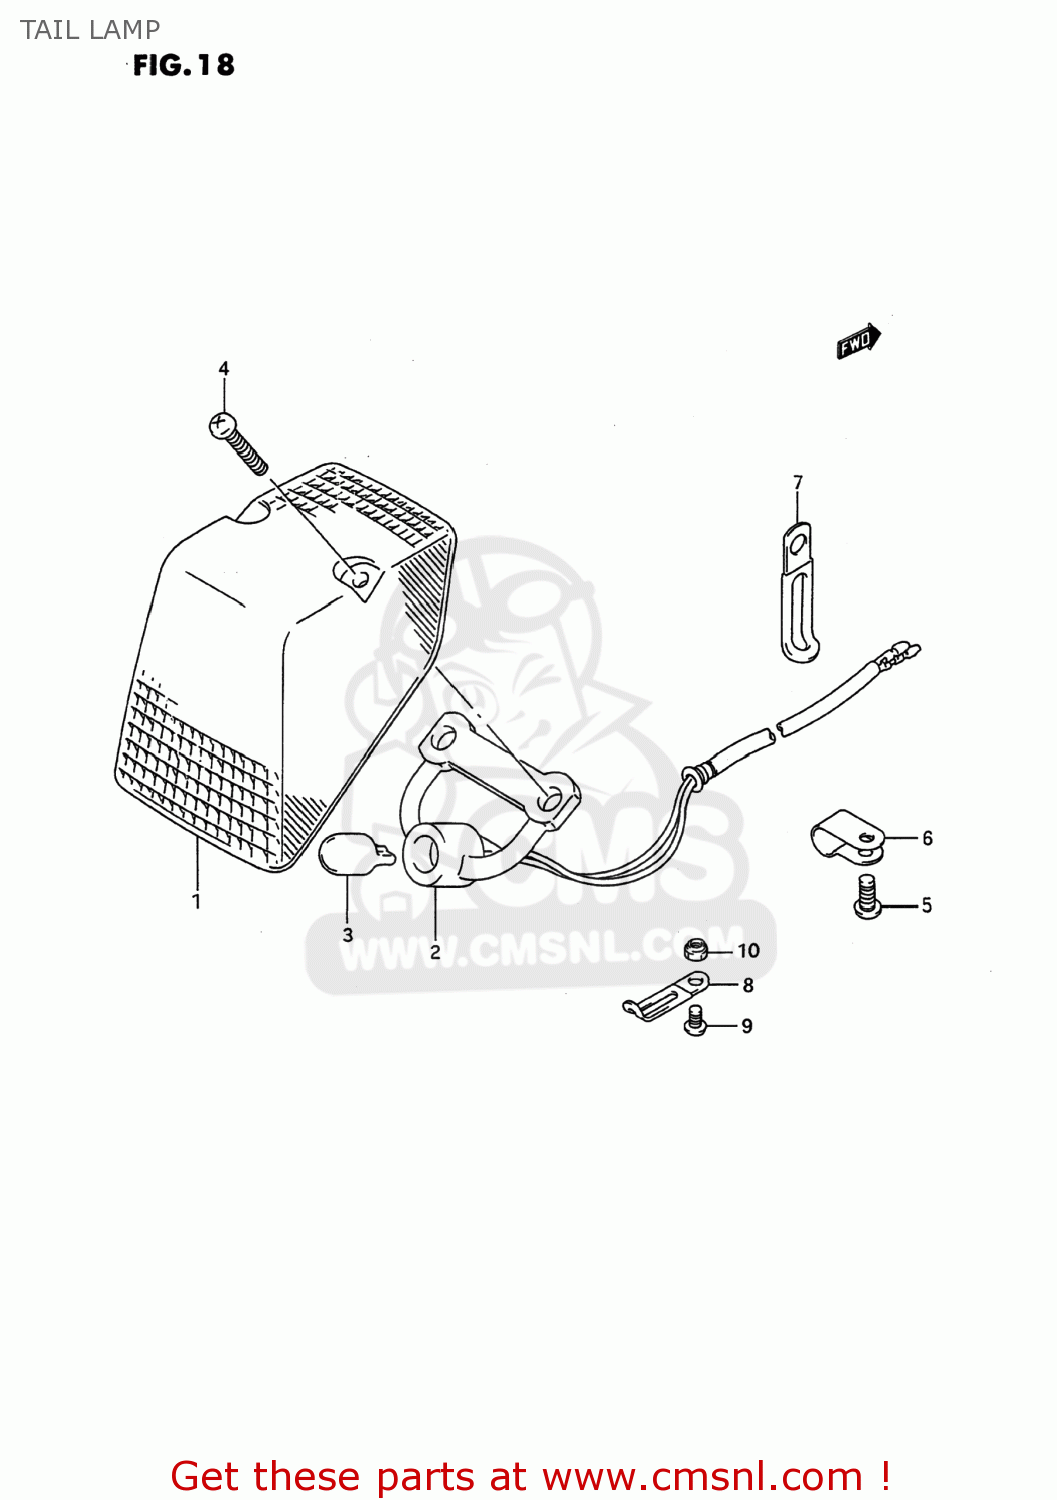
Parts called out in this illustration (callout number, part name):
1	LENS
2	SOCKET & CORD,RR COMBINATION
3	BULB
4	SCREW
5	SCREW
6	CLAMP
7	CLAMP L:62
8	CLAMP(L:45)
9	SCREW
10	NUT
